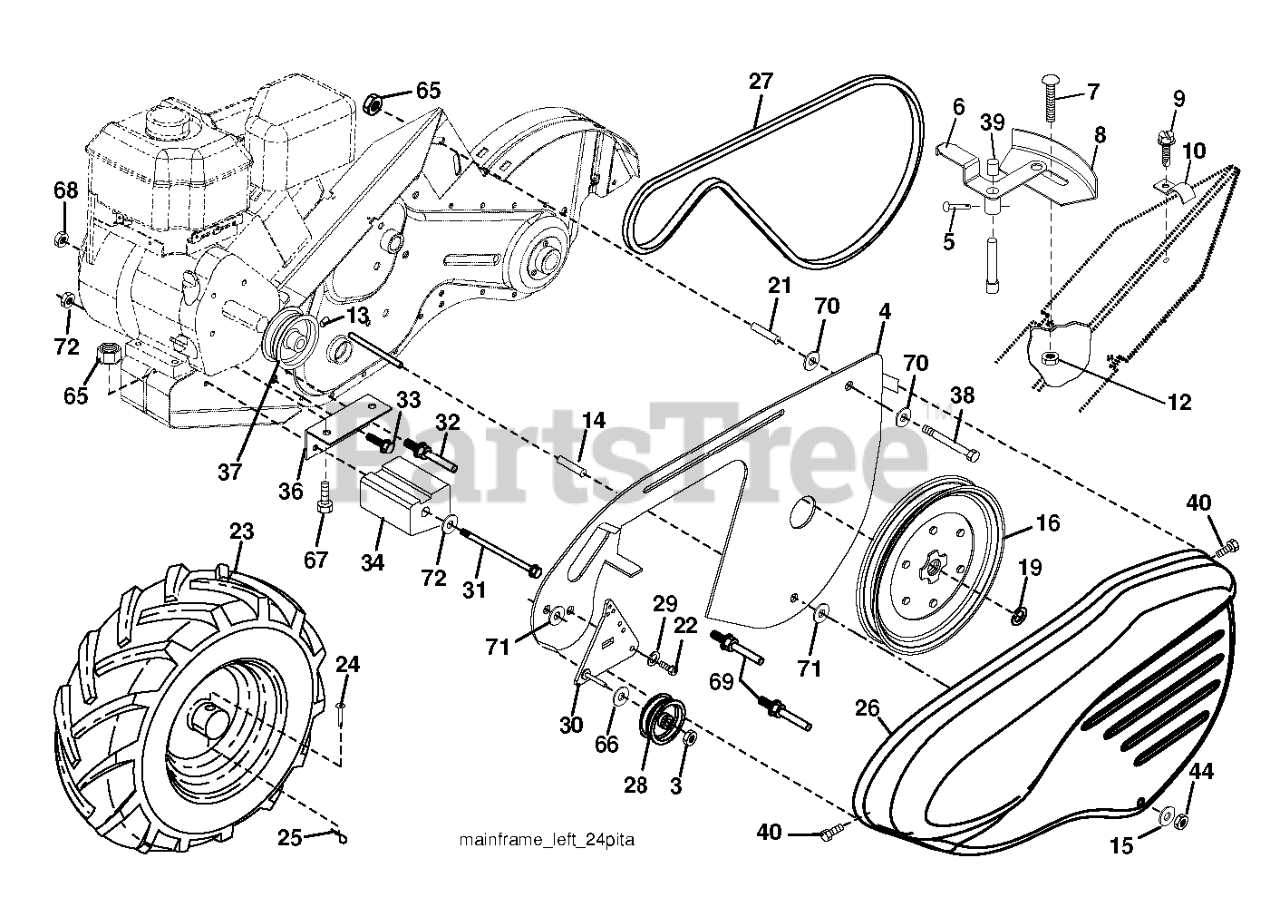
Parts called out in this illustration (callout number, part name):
3	LOCKNUT
4	SHIELD.INNER.BELT.GUARD.RT.BLA
5	PIN.SPIROL.FLARED
6	LEVER ASM CRT
8	PANEL.INDICATOR.SHIFT.BLACK
9	TAPPING SCREW
10	CONDUIT.CLIP.PLATED
12	NUT
14	SPACER-SPLIT.327 X .42
15	WASHER
16	SHEAVE, TRANSMISSION
19	RETAINING RING LT
21	SPACER SPLIT
23	WHEEL.ASM.CRT.LH.13X5X6.SILVER
24	RIVET,DRILLED
25	RETAINER M
26	GUARD.BELT.TILLER.ORANGE
27	V-BELT
28	PULLEY-IDLER TI
30	BRACKET.IDLER.ASM.LONG
31	BOLT.FIN.HEX.3/8-16UNC X 11.5
32	SHIFT ARM CRT
33	BOLT
34	COUNTERWEIGHT.LH
36	BRACKET.REINFORCEMENT.LH.PNT
37	RP.ENGINE PULLEY
38	BOLT
39	CAP.PLUNGER.BLACK
40	SCREW.HEX.WSH.SLT.#10-24X.50
44	NUT.71038.31-18.HEX.NYLOCK
65	LOCKNUT-FLANGE 5/16-18
66	WASHER
67	BOLT
69	KEEPER.BELT.ENGINE
70	STEEL WASHER
71	WASHER
